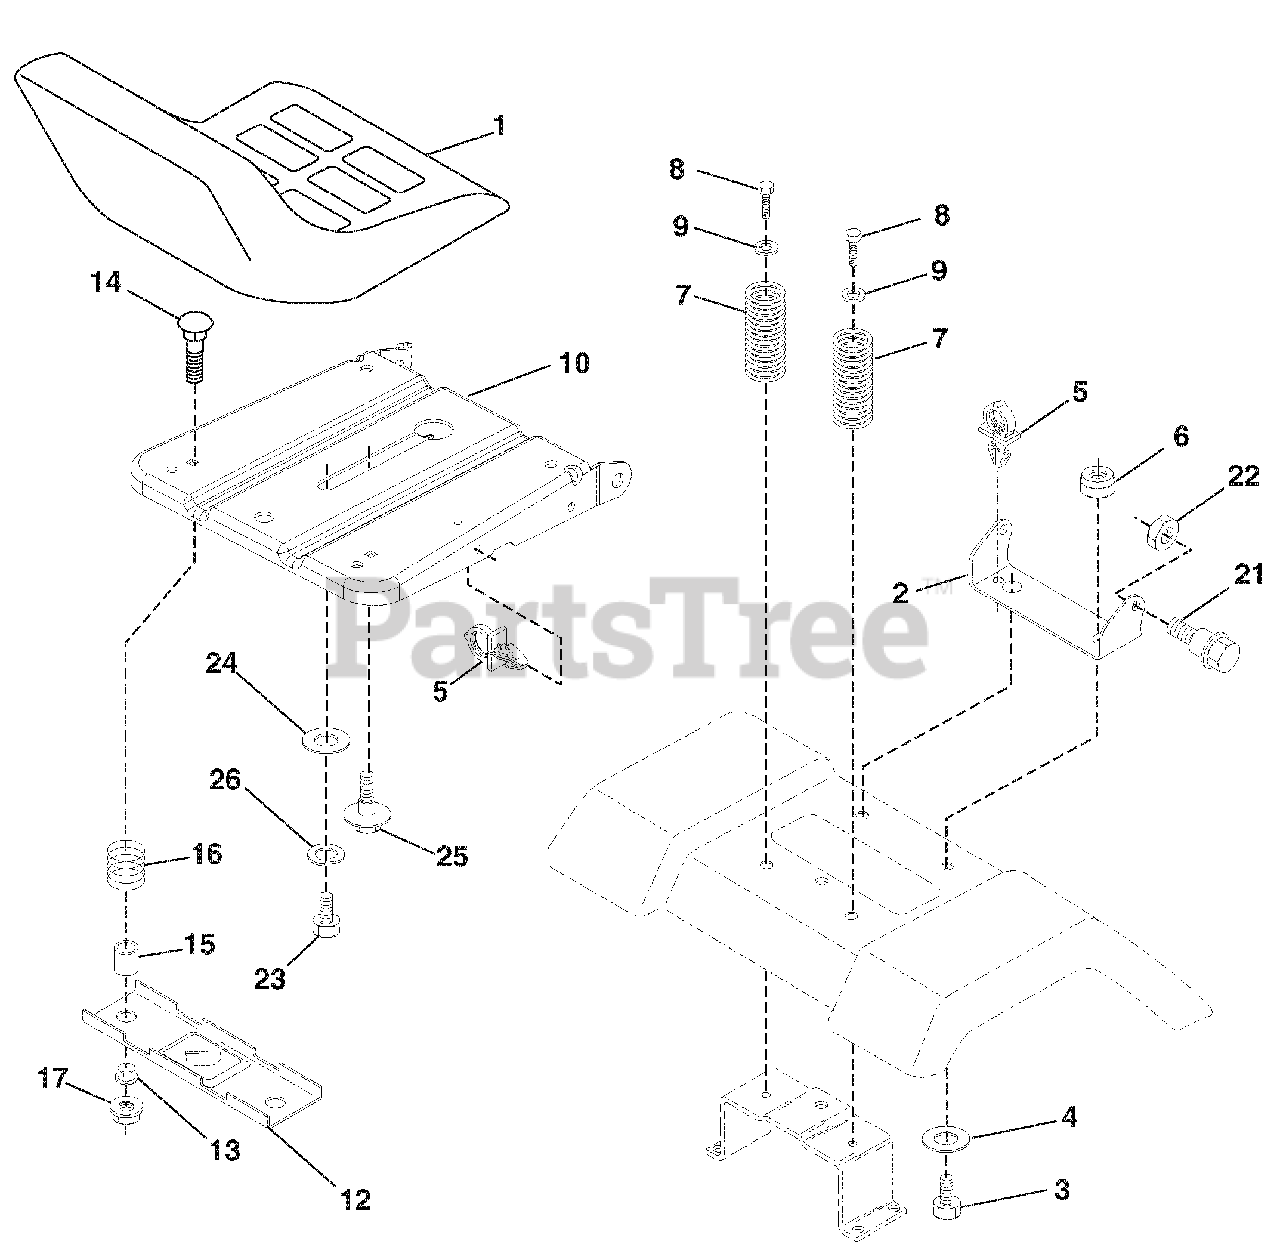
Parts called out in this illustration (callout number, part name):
2	Bracket Seat Pivot
3	Bolt Hex 3/8 - 16 x 1
4	Washer 13/32 x 1 x10 Ga.
5	CLIP.PUSH-IN.HINGED
6	Locknut, Washer Insert 3/8-16
7	SPRING.SEAT.CPRSN.2.250.BLK.ZI
8	SCREW.3/8-16X1.SMGML.TAP/R.BLK
9	Washer 13/32 x 1 x 14 Ga.
10	Pan Pnt Seat
12	Bracket Pnt Mounting Switch
13	BUSHING.SNAP.BLK.NYL..50 ID.
14	BOLT.RDHD.SHT.NK.1/4-20X1-1/2
15	SPACER.SPLIT..28X.96.YEL.ZINC
16	Spring Cprsn
17	NUT.LOCK.1/4 LGE.FLG.GR.5.ZINC
21	BOLT.SHLD.5/16-18 UNC-2A.BLK D
22	Locknut, Washer Insert 5/16-18
23	Bolt Hex
24	WASHER.17/32 X 1-3/16 X 12 GA.
25	Bolt Shoulder 5/16-18 x .62
26	Washer Lock Hvy Hlcl Spr 1/2
